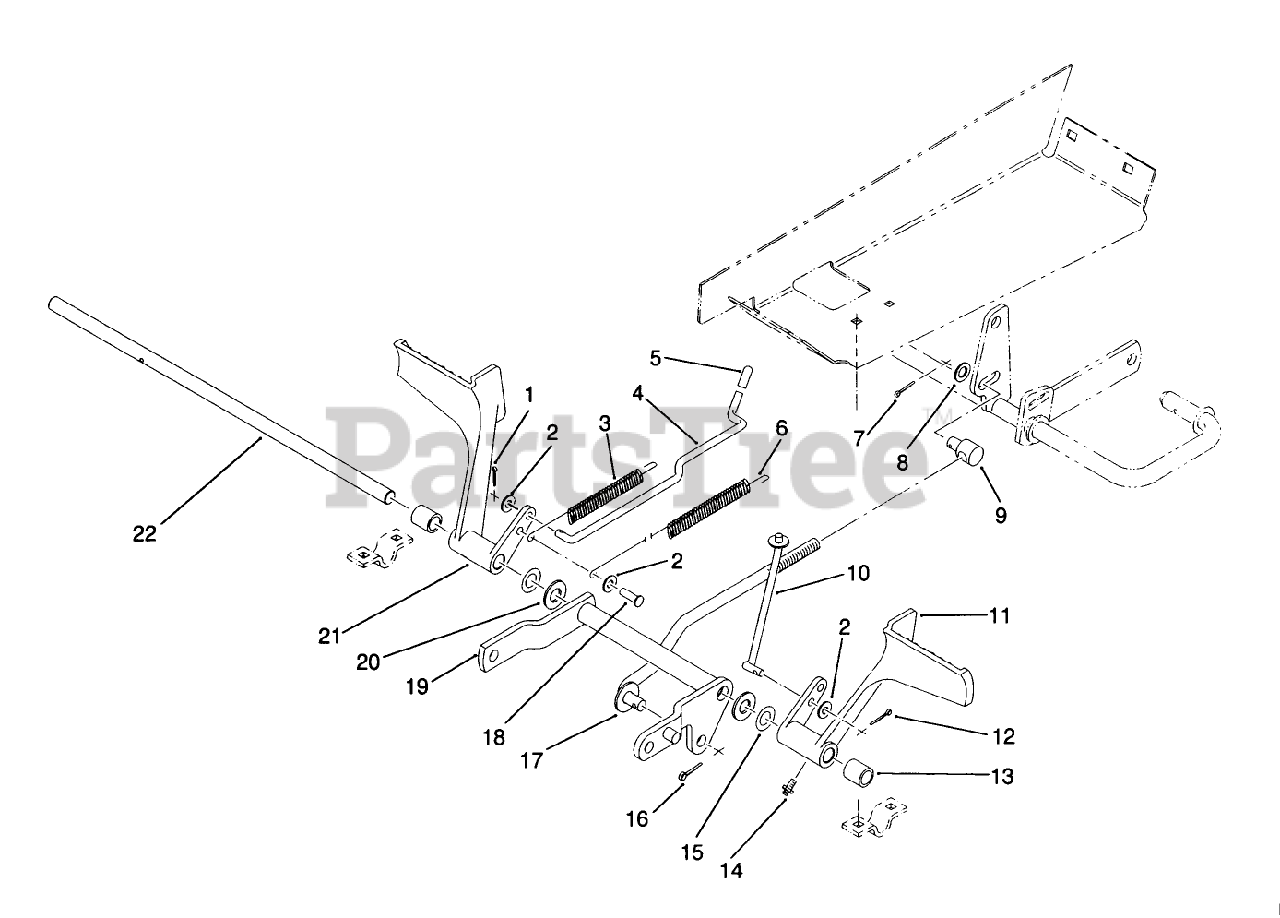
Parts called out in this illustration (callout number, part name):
3	SPRING-BRAKE
4	ROD-BRAKE LOCK
6	SPRING-EXTENSION
13	SPACER
15	WASHER-WAVE
20	WASHER-FLAT
22	SHAFT *R
